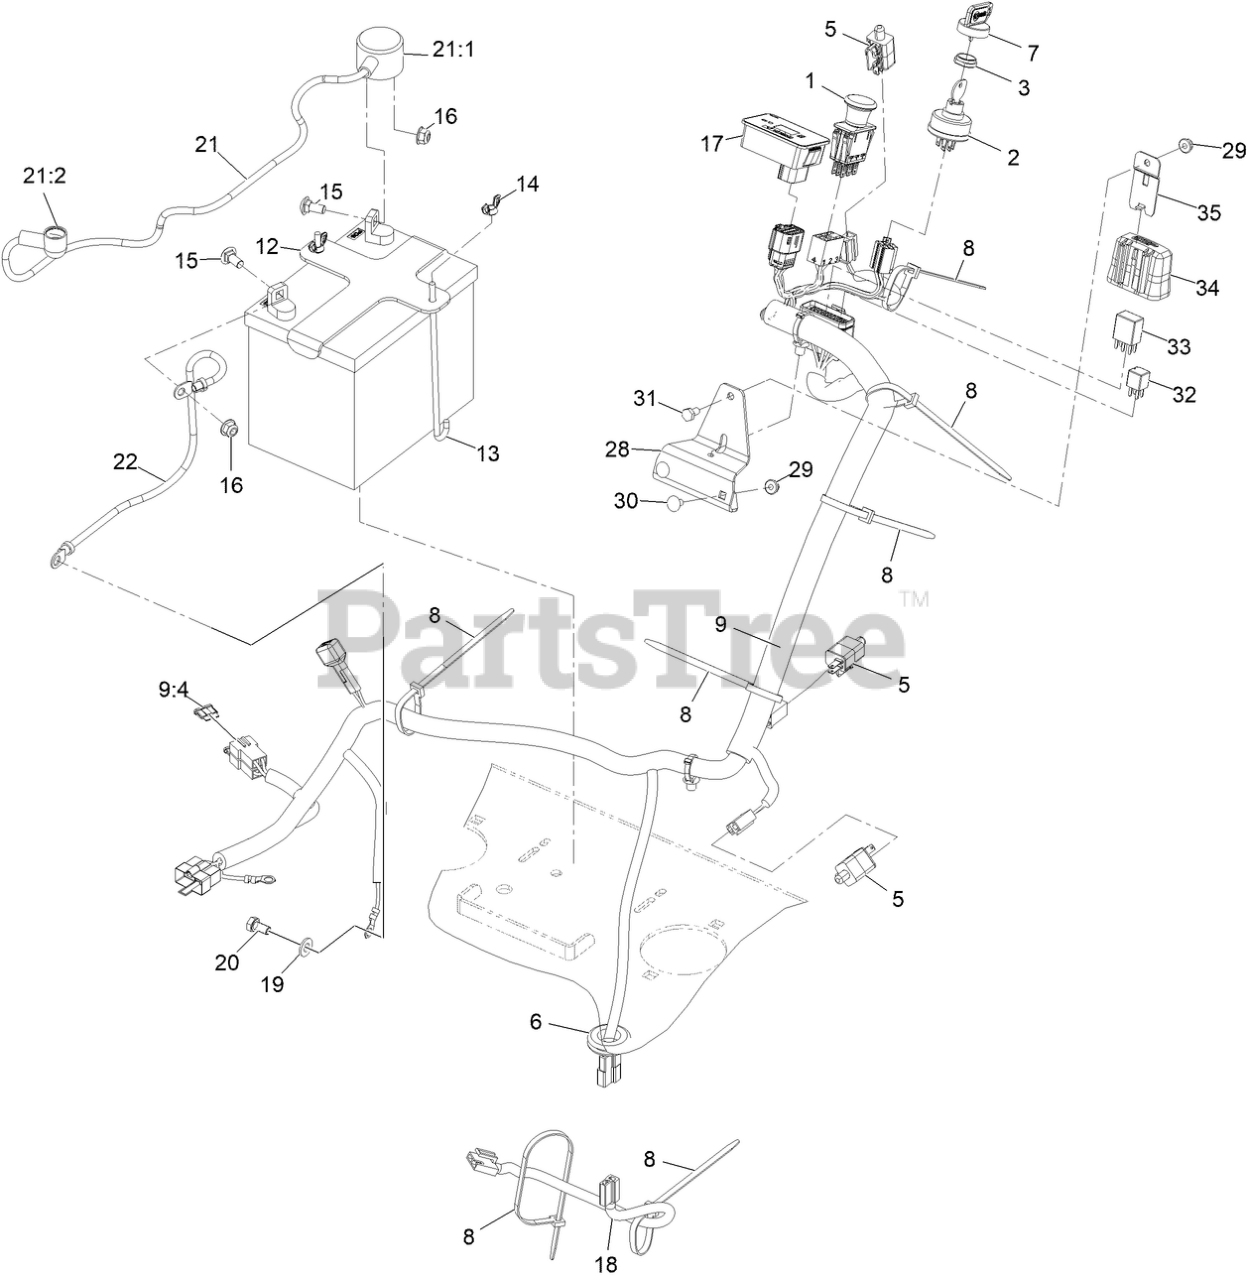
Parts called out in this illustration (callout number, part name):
1	SWITCH-PTO
2	SWITCH, KEY START
3	NUT-SWITCH, IGNITION
6	GROMMET
7	KEY-IGNITION
8	TIE-CABLE
9	HARNESS-WIRING
9:4	FUSE-BLADE TYPE, 20 AMP
12	BRACKET, BATTERY HOLD DOWN
13	BOLT-HOLDDOWN
14	WINGNUT
15	BOLT-CARR
16	NUT-HF, NI
17	MODULE-HOUR METER
18	HARNESS-CLUTCH PIGTAIL
19	WASHER-PLAIN
20	SCREW-HH
21	POSITIVE BATTERY CABLE AS
21:1	INSULATOR-SOLENOID
21:2	INSULATOR-BATTERY
28	BRACKET, MOUNTING PDM
30	SCREW-CARR
31	SCREW-HH
32	RELAY-MICRO
33	RELAY-MICRO 280, SPDT
34	COVER-BLOCK, FUSE
35	CLIP-MOUNTING
